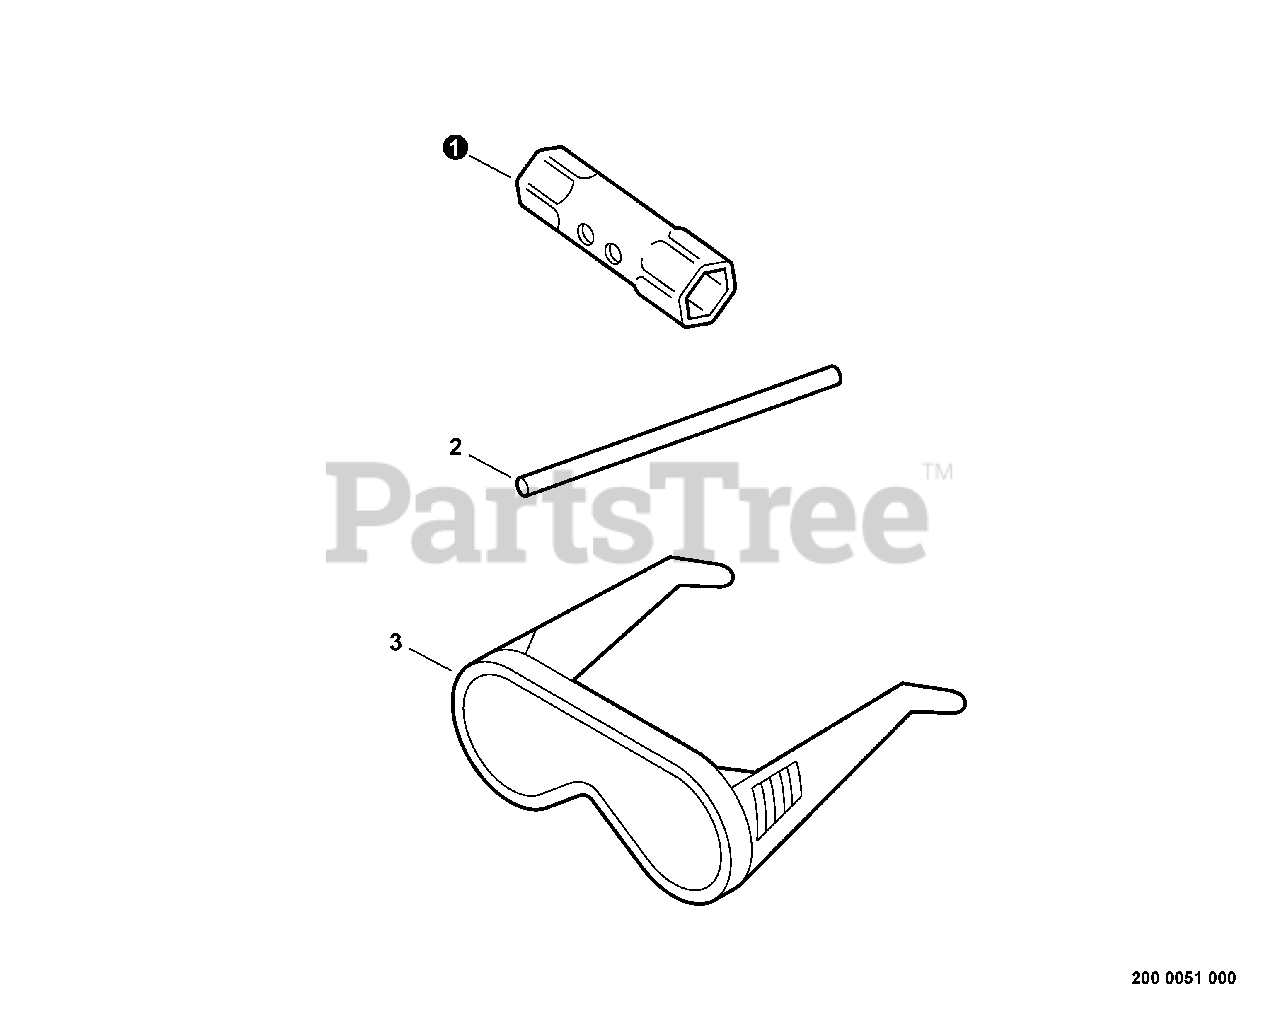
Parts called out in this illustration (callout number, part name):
1	SOCKET WRENCH 17×14.5 MM
2	TOOL, LOCKING 5×120 MM
3	GLASSES, SAFETY
